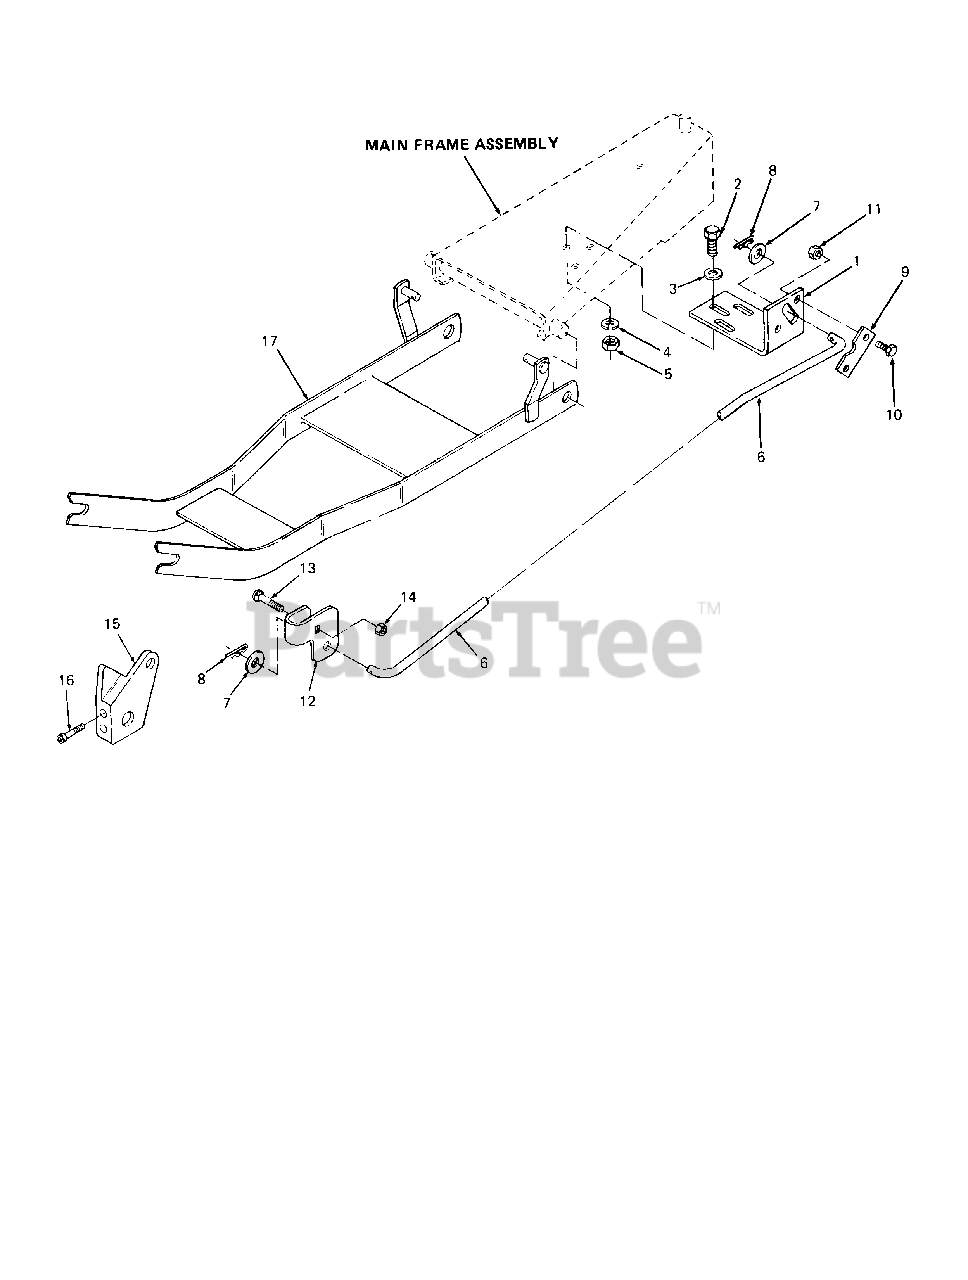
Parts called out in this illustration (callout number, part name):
3	Washer, Flat, 1/2 X 1.25 X .10 Thk
4	Washer, Lock, 1/2
5	Nut, Hex, 1/2-13 GR5
8	Pin, Internal Cotter
9	Bar, Lockout
10	Screw, Hex Cap, 3/8-16 X 1.0 Lg GR5
11	Nut, Hex, 3/8-16 GR5
13	Bolt, Carriage, 3/8-16 X 1.75 Lg GR5
14	Nut, Hex Center Lock, 3/8-16 GR5
15	Bracket, Hydraulic Lift
16	Screw, Socket Hd Cap, 5/16 X 1.5 Lg
